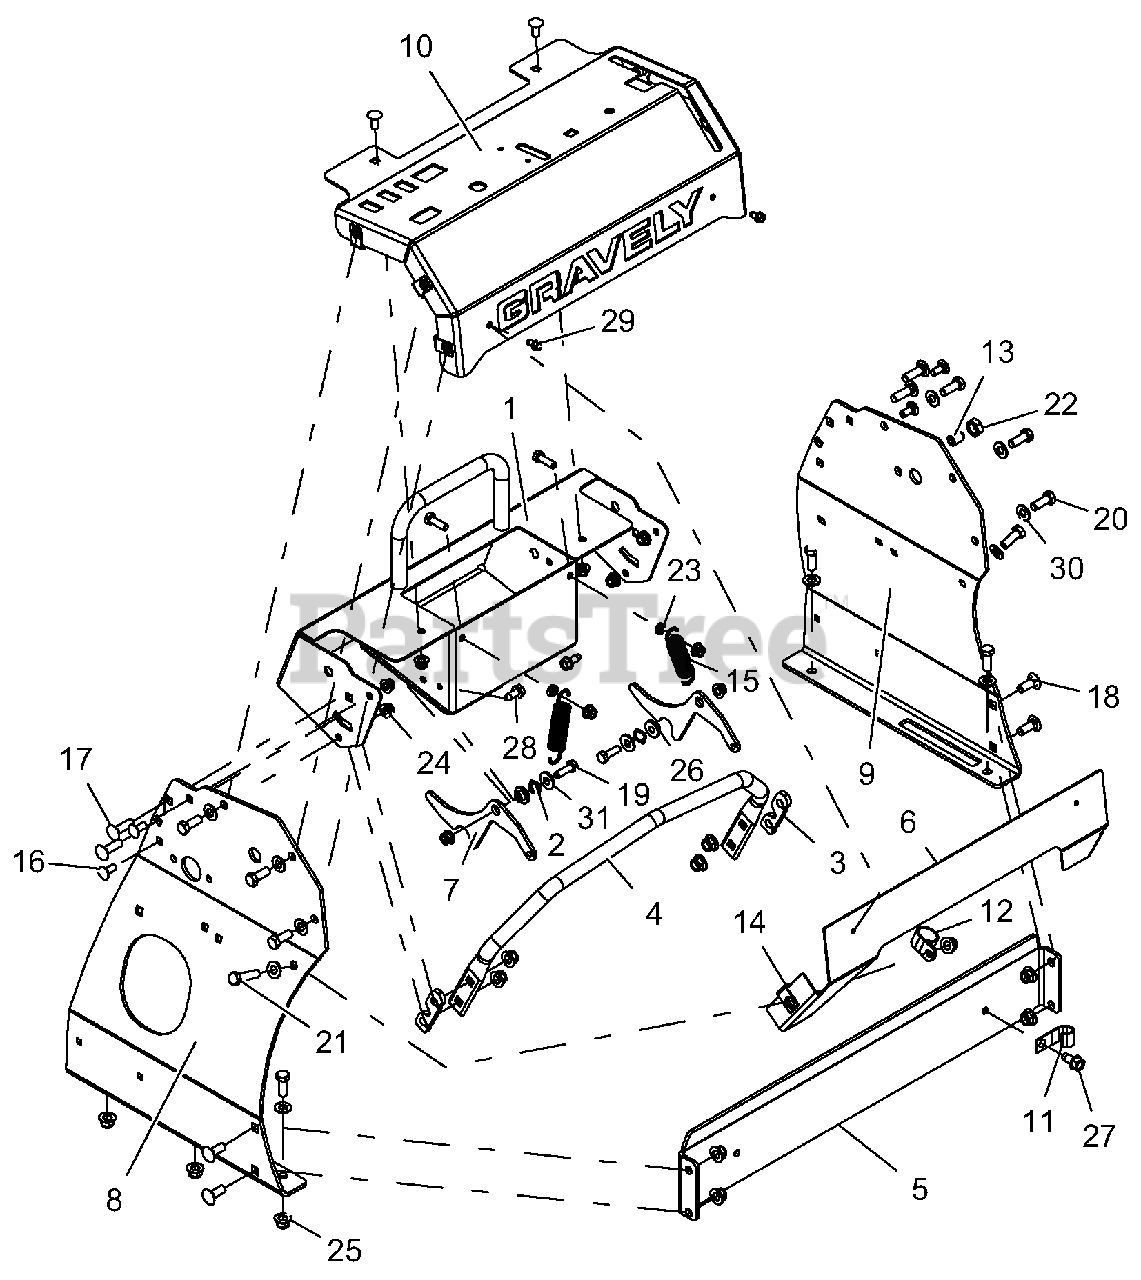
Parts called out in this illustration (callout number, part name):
1	WLDMT, CONTROL PANEL, PRO-STANCE
2	WAVE WASHER .531 x .781 x .125 FH
3	SHIM, BAR 5 DEG SPEED - BLACK
4	STOP, FORWARD STEERING
5	STIFFENER, TOWER
6	PLATE, FRONT BACKER
7	LATCH, PAD MOUNT
8	PANEL, TOWER RH, PRO-STANCE
9	PANEL, PROSTANCE LH TOWER
10	PANEL, CONTROL - PRO-STANCE
12	CLAMP, CUSHIONED STEEL REV
13	BALL SPRING PLUNGER, .500-13
14	NUT, RTNR .375-16 x .37
15	SPRG, EXTENSION
16	BLT-RDHDSQNK .31-18 x .75 G5 YWZC
17	BLT-RDHDSQNK .38-16 x 1.25 G5 YWZC
18	BLT-RDHDSQNK .38-16 x 1.00 G5 YWZC
19	BLT-HEX .31-18 x 1.00 GR5 YWZC
20	BLT-HEX .38-16 x 1.00 GR5 YWZC
21	BLT-HEX .38-16 x 1.50 GR5 YWZC
22	NUT, JAM .500-13 YWZC
23	@NUT-LK-CTR-JAM .31-18 YWZC
24	NUT-LK-NYL-FLG .31-18 YWZC
25	NUT-LK-NYL-FLG .38-16 YWZC
26	BSHG, FLG .32 x .500 .344 x .880
27	SCR-TAP .38-16 x .75 HWH TR YWZ
28	SCR-TAP .31-18 x .75 HWH TR YWZ
29	SCR-TAP .25-20 x .50 HWH TR YWZ
30	WSHR-FL-STL .406 x .812 x .065 YWZ
31	WSHR-FL-STL .38 x .875 x .083 YWZC
